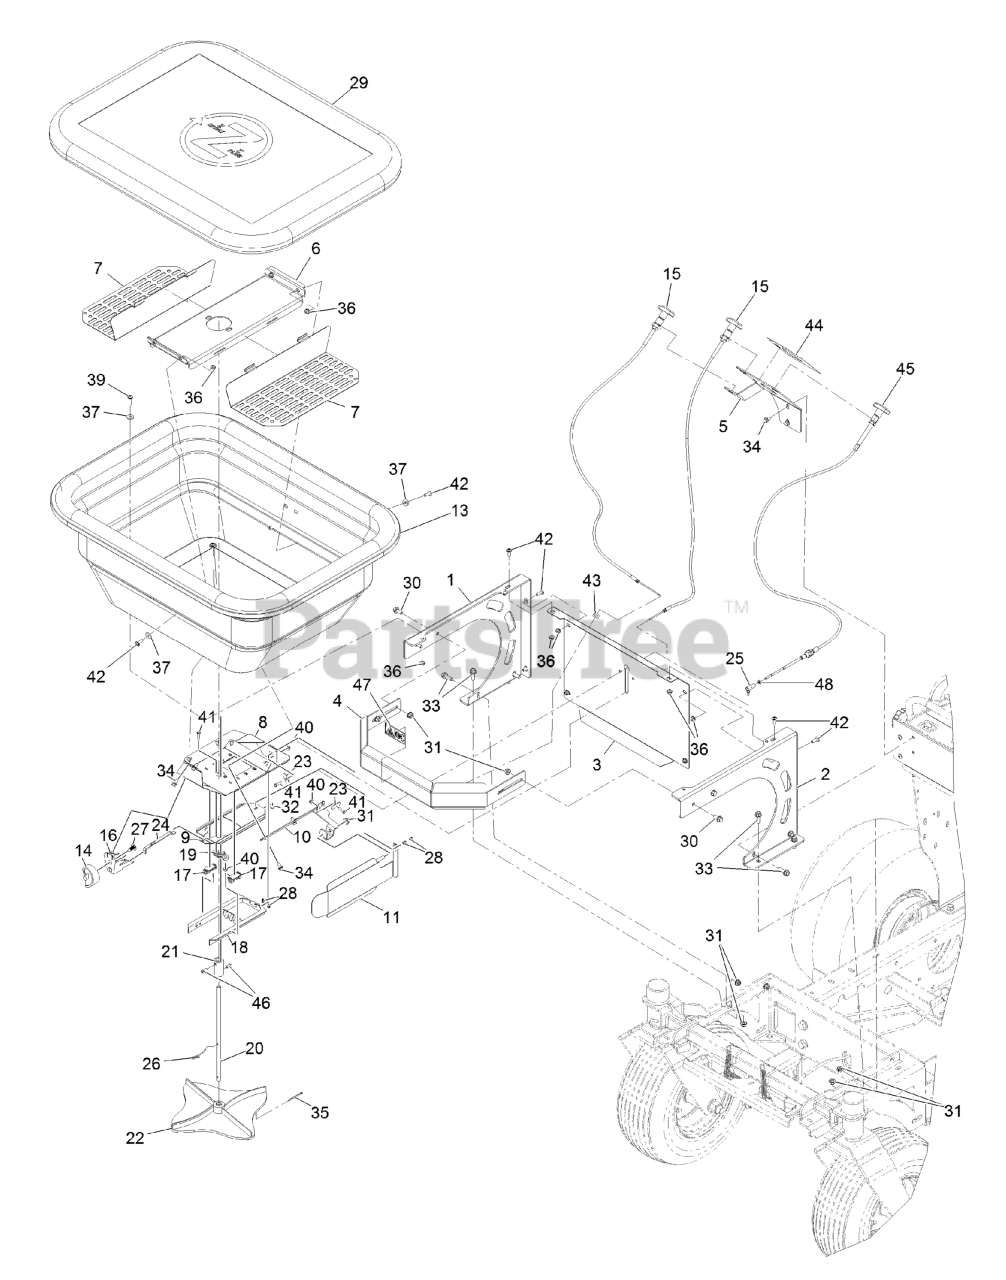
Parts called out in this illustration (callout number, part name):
1	Side-Hopper, Rt
2	Side-Hopper, Lt
3	Backshield-Hopper
4	BUMPER-FRONT, HOPPER
5	Mount-Speedometer
6	PAN-HOPPER, 220
7	SCREEN-HOPPER, 220
8	PLATE-BASE, HOPPER
9	Slide-Door, Hopper
10	Mount-Deflector, Side
11	Deflector-Side, Spreader
13	HOPPER-220LB
14	DIAL
15	CABLE-PUSH/PULL
16	MOUNT-DIAL
17	GUIDE-RATE, GATE
18	DIFFUSER
19	BEARING-FLANGE
20	SHAFT-HOPPER, 220
21	COUPLER-SS
22	SPINNER-SPREADER
23	RETAINER, CABLE
24	LINKAGE-GATE, RATE
25	BALL JOINT-SS
26	WIRE-AGITATOR
27	CLIP
28	RETAINER-CABLE, WIRE
29	COVER-HOPPER, LARGE
30	SCREW-HHF
31	Nut-Hex Flange
32	Nut,NYL Lock,#10-32,ST/ST 18-8
33	SCREW-HHF
34	SCREW-HHF
35	PIN-COTTER
36	Nut-Hex Flange
39	Screw-Hsbhf
40	Nut-Hex Flange
41	SCREW-HH
42	Screw-Hsbhf
43	Grommet-Rubber
44	DECAL-HOPPER CONTROL
45	CABLE-PUSH/PULL
46	Screw-SQH
47	Decal-Dismemberment Hazard
48	Nut,Hex Jam Mch Scr,10-32,Sst
